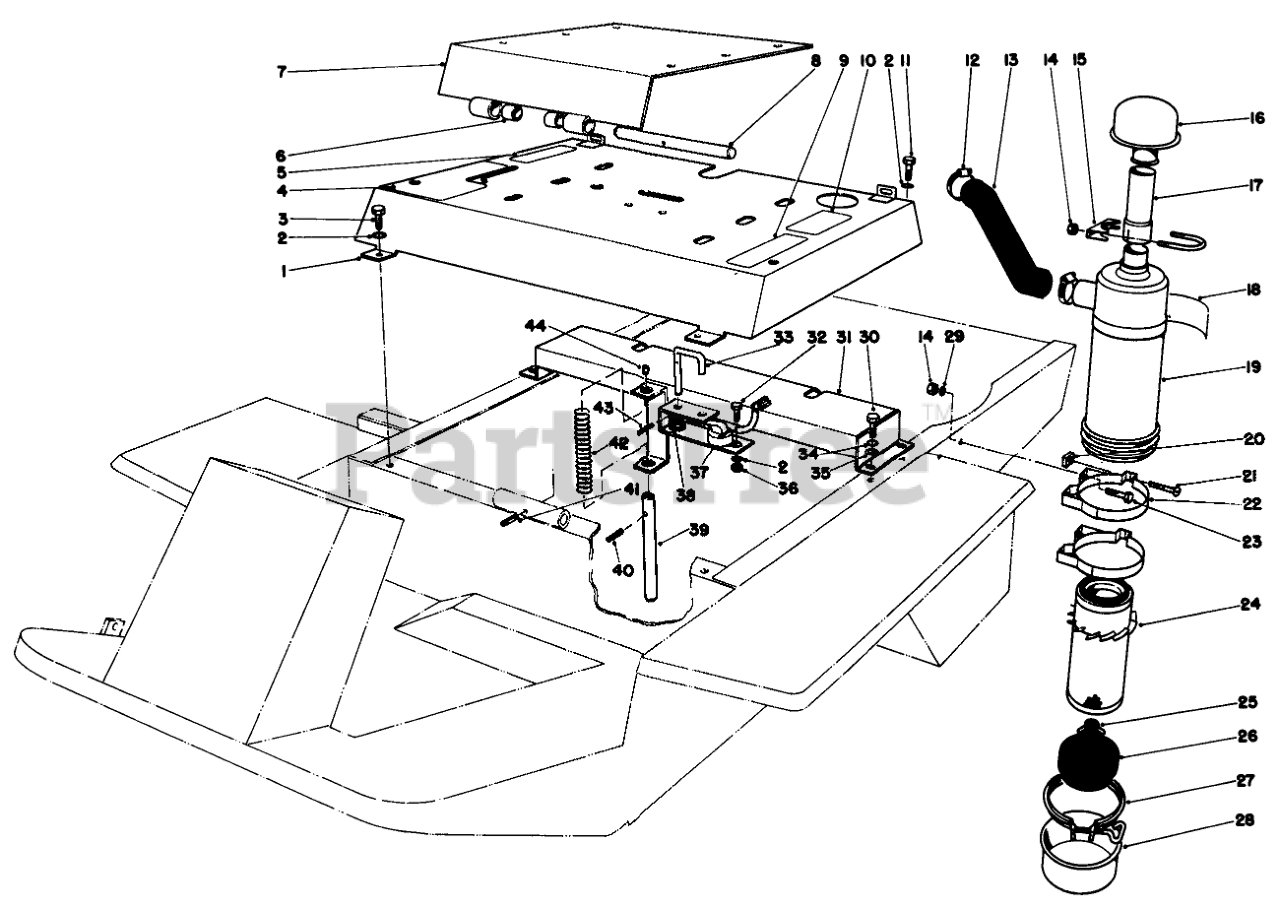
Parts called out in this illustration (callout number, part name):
1	Cover-Seat Support (Incl. Ref. #4, 5, 9 & 10)
2	WASHER-LOCK
3	SCREW THD 1/4 20 5/8
4	Decal Hydraulic Lift
5	Decal Caution
6	.503ID X .875LG BSHG
7	Seat Mounting (Incl. Ref. #6)
8	SHAFT-PIVOT, SEAT
9	Decal Caution
10	DECAL-REFUELING
11	SCREW-HH
12	CLAMP-HOSE
14	NUT-HEX
15	CLAMP-MUFFLER
17	Tube-Air Cleaner
18	DECAL-INSTALLATION
19	Air Cleaner Assembly (Incl. Ref. #18 & 24-28)
20	NUT-SQUARE
21	SCREW
22	Band Assembly Mounting (Incl. Ref. #20 & 21)
23	SCREW-HH
24	ELEMENT ASM
25	NUT AND GASKET ASM
26	SKIRT-BAFFLE
27	CLAMP ASM
28	A/C CUP ASM
29	Lockwasher
30	SCREW-HH
31	Seat Support
32	SCREW-HH
33	SEAT SWITCH PIN
34	WASHER-LOCK
35	WASHER-FLAT
36	NUT-HEX
37	SWITCH ARM
38	SPRING
39	PIN-SWITCH, SEAT
40	PIN-ROLL, SLOTTED
41	PIN-ROLL, SLOTTED
42	SPRING-COMP
43	PIN-SPRING
44	PIN-PEDAL
